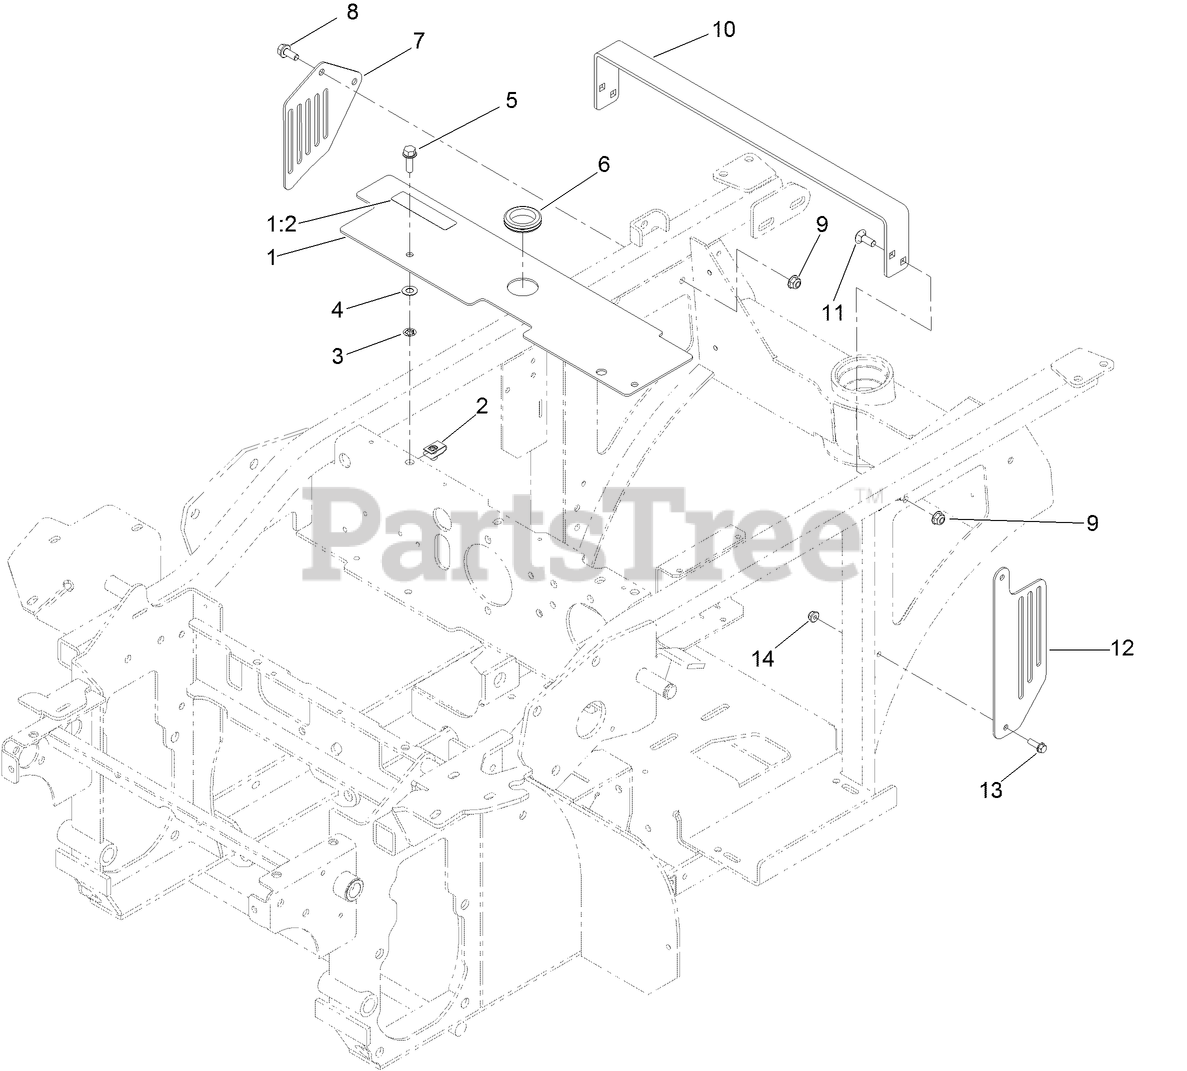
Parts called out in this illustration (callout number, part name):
1	PUMP GUARD ASM
1:2	DECAL-WARNING
2	NUT-CLIP, U
3	NUT-PUSH
4	WASHER-THRUST
5	SCREW-HHF
6	GROMMET-RUBBER
7	GUARD-MUFFLER, RH
8	SCREW-HHF
9	NUT-HF, NI
10	GUARD-MUFFLER, TOP
11	SCREW-CARR
12	GUARD-MUFFLER, LH
13	SCREW-HWH
14	NUT-HF
